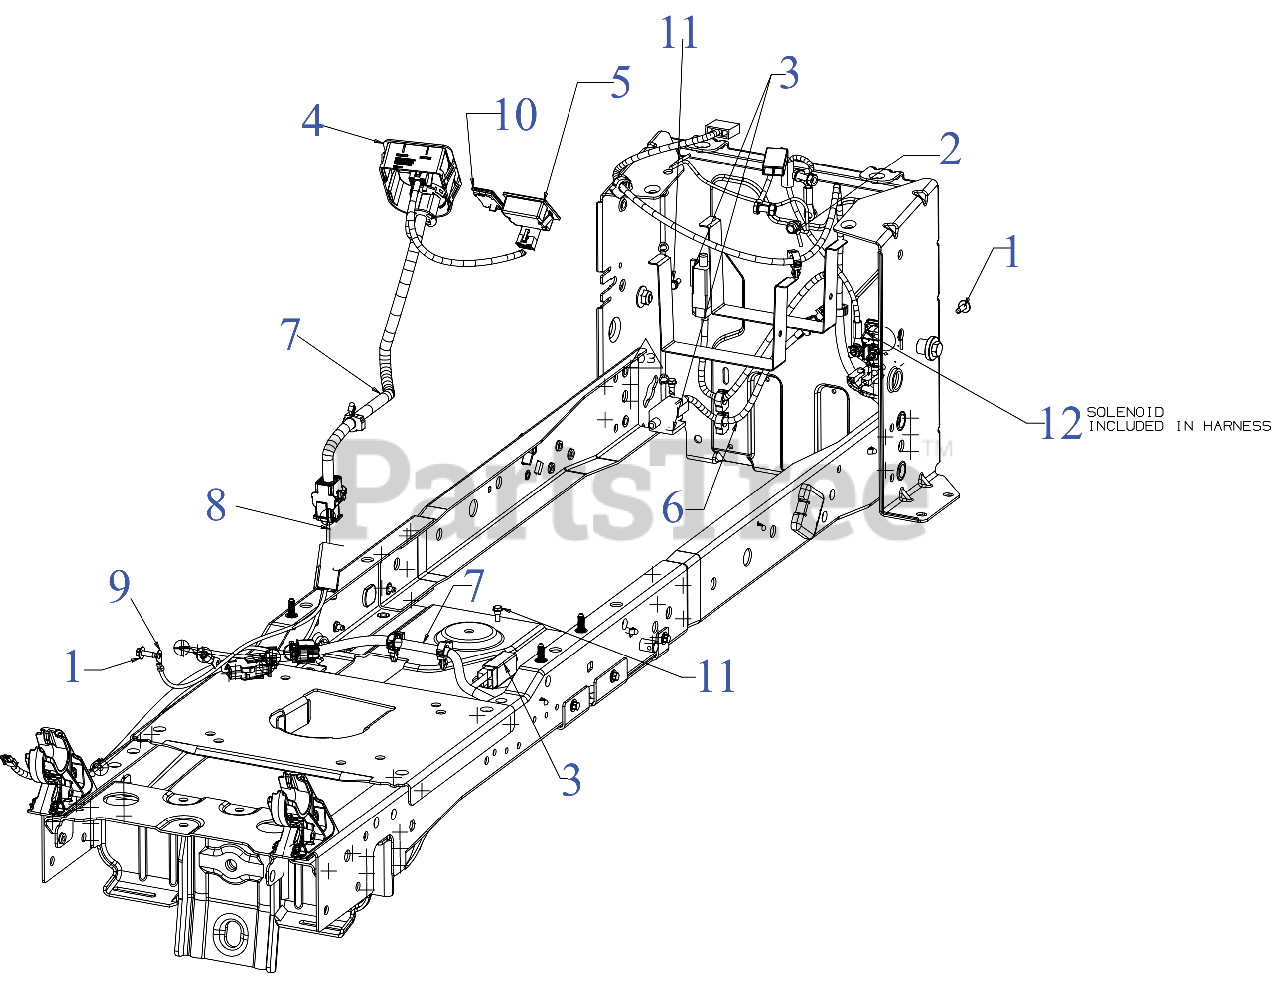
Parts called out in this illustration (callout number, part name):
1	SCREW M6-1 x .625
2	SCREW 1/4-20X.625
3	INTERLOCK SWITCH (NO/NC)
4	IGNITION MODULE SWITCH RMC (MAN PTO BLK)
5	HOUR METER/SERVICE MINDER
5	Cub Cadet HOUR METER KIT
5	Troy-Bilt HOUR METER KIT
6	REVERSE HARNESS
7	MAIN HARNESS (M-PTO/RMC/HRMTR)
8	DASH HARNESS (M-PTO/RMC/HRMTR)
9	JUMPER HARNESS (E GOV)
11	SHOULDER SCREW
12	12V SOLENOID
